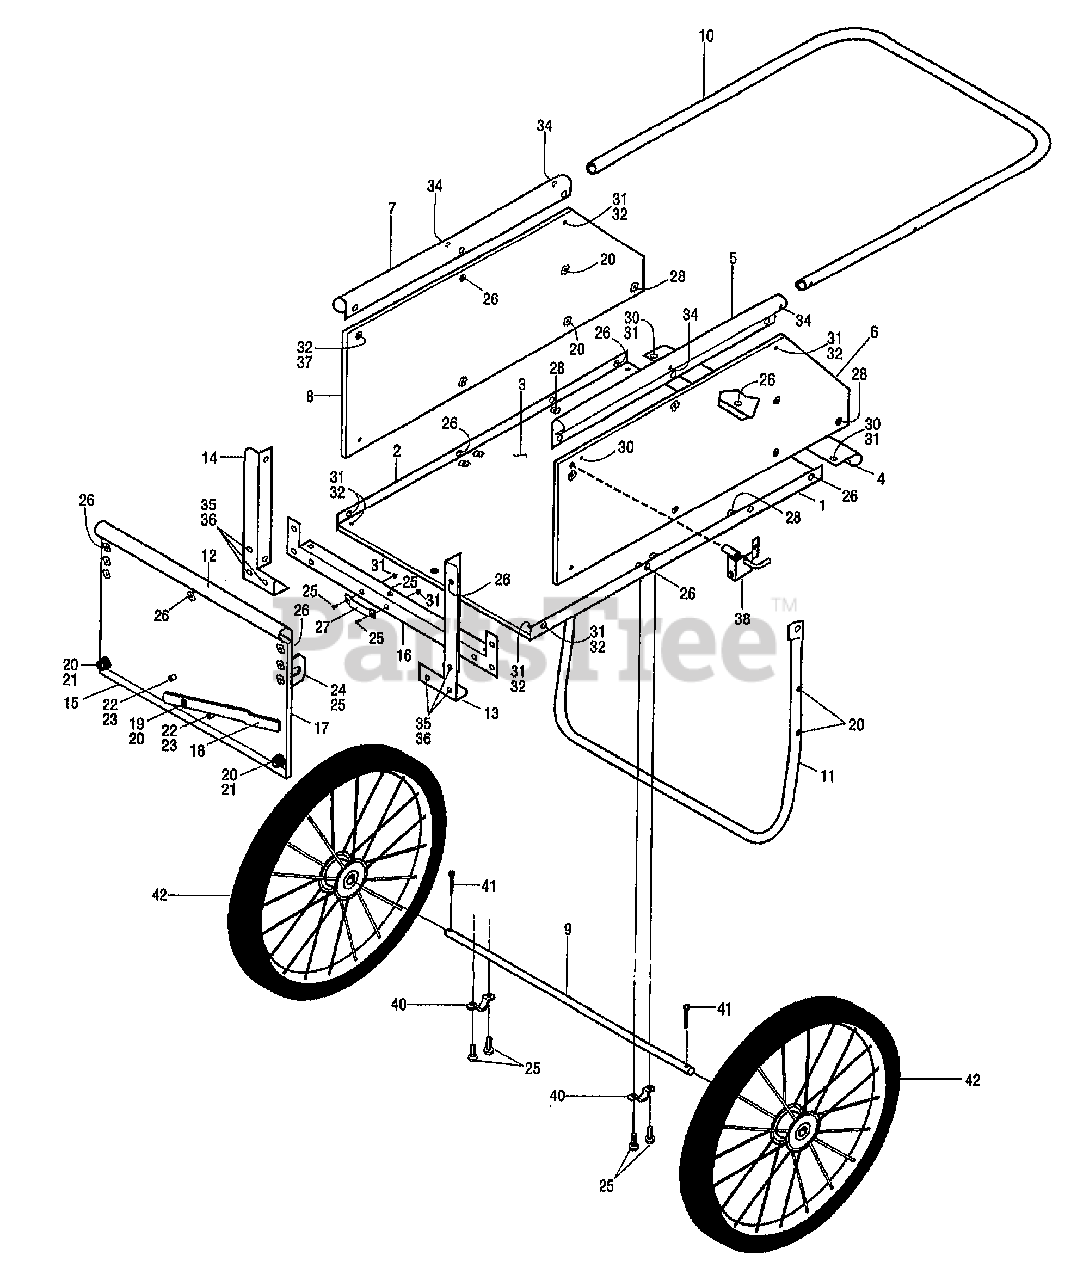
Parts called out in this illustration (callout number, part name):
1	ANGLE-BOTTOM 20 SOLID FRONT LT
2	ANGLE-BOTTOM 20 SOLID FRONT RT
3	PANEL-BOTTOM W/TNUTS
4	PROTECTOR-REAR M20
5	SLEEVE-20 HANDLE LT
6	PANEL-LFT W/TNUTS M20
7	SLEEVE-20 HANDLE RT
8	PANEL-RH W/TNUTS M20
9	AXLE-MODEL 20
10	MISC 20 HANDLE
11	STAND-M20 SF/DF
12	PROTECTOR-20 TOP EDGE
13	SUPT-20 SWING FRONT SIDE LT
14	SUPT-20 SWING FRONT SIDE RT
15	EDGE-BOTTOM M20
16	SUPT-BOTTOM 20 SWING FRONT
17	PANEL-FRONT DOOR W/TNUTS
18	LATCH-20&26 SWING FRONT
19	SPACER-20&26 SWING FRONT
20	BOLT-1/4 X 1 1/4 PAN HD
21	CASE FEET
22	BUSHING-.31X.188X.38
23	SCR-WOOD RHS M8X.75 ZP
24	HINGE-20&26 SWING FRONT
25	BOLT-1/4 X 5/8 PAN HD
26	SCR-PH 1/4-20 X .5
27	PLATE-LATCH 20&26 SWING FRONT
28	NUT-HT/LK 1/4-20X.375
30	BOLT-SLPH 1/4-20 X.875-ZP
31	NUT-LK 1/4-20
32	BOLT-1/4 X 1 PAN HD
34	SCR-PHS M6X.5 ZP
35	SCR-HH 5/16-18X.5 GD5 YEL
36	NUT-H/LK 5/16-18 NYLOCK
37	PIVOT-HINGE M26 R/D
38	ASSM-20&26 PLUNGER
40	CLAMP-AXLE 20 & 26
41	PIN-COTTER 3/32 X 1 1/4
42	WHEELS-T/B M20 CART BOX 2
